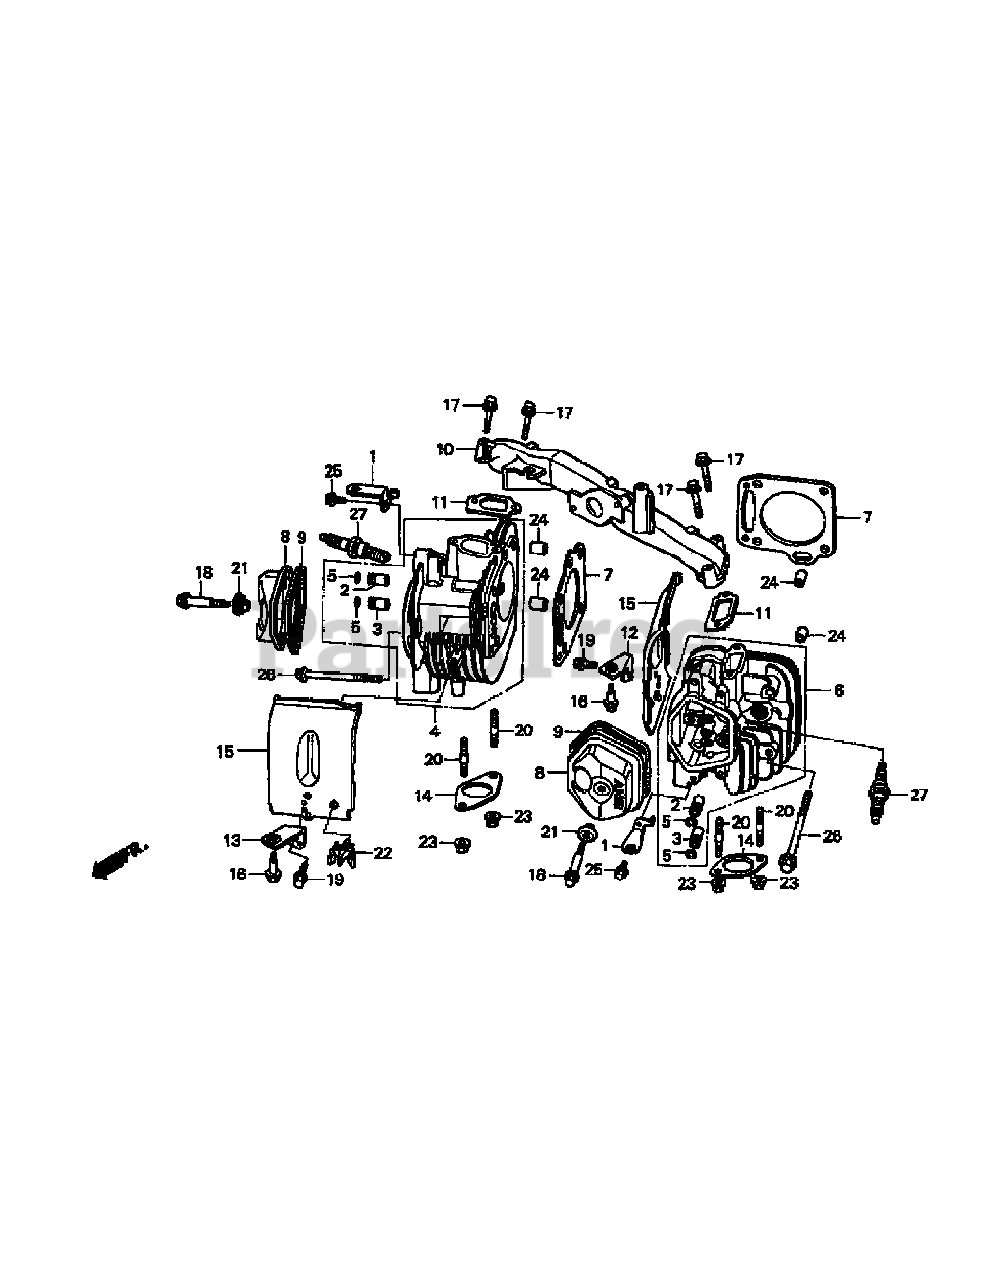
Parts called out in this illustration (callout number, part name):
1	Engine Hanger
2	Intake Valve Guide (OS)
3	Exhaust Valve Guide (OS)
4	Cylinder Head #1
5	Valve Guide Clip
6	Cylinder Head #2
7	Cylinder Head Gasket
8	Head Cover
9	Head Cover Gasket
10	Inlet Manifold
11	Inlet Manifold Gasket
12	Air Cleaner Bracket, R.H.
13	Air Cleaner Bracket, L.H.
14	Exhaust Pipe Gasket
15	Head Shroud
16	Flange Bolt (6mm)
17	Socket Bolt (8x45)
18	Head Cover Bolt
19	Flange Bolt (6x14)
20	Stud Bolt (8x22)
21	Head Cover Washer
22	Fuel Tube Clip
23	Flange Nut (8mm)
24	Dowel Pin (12x20)
25	Flange Bolt (8x20)
26	Flange Bolt (10x80)
27	Spark Plug
